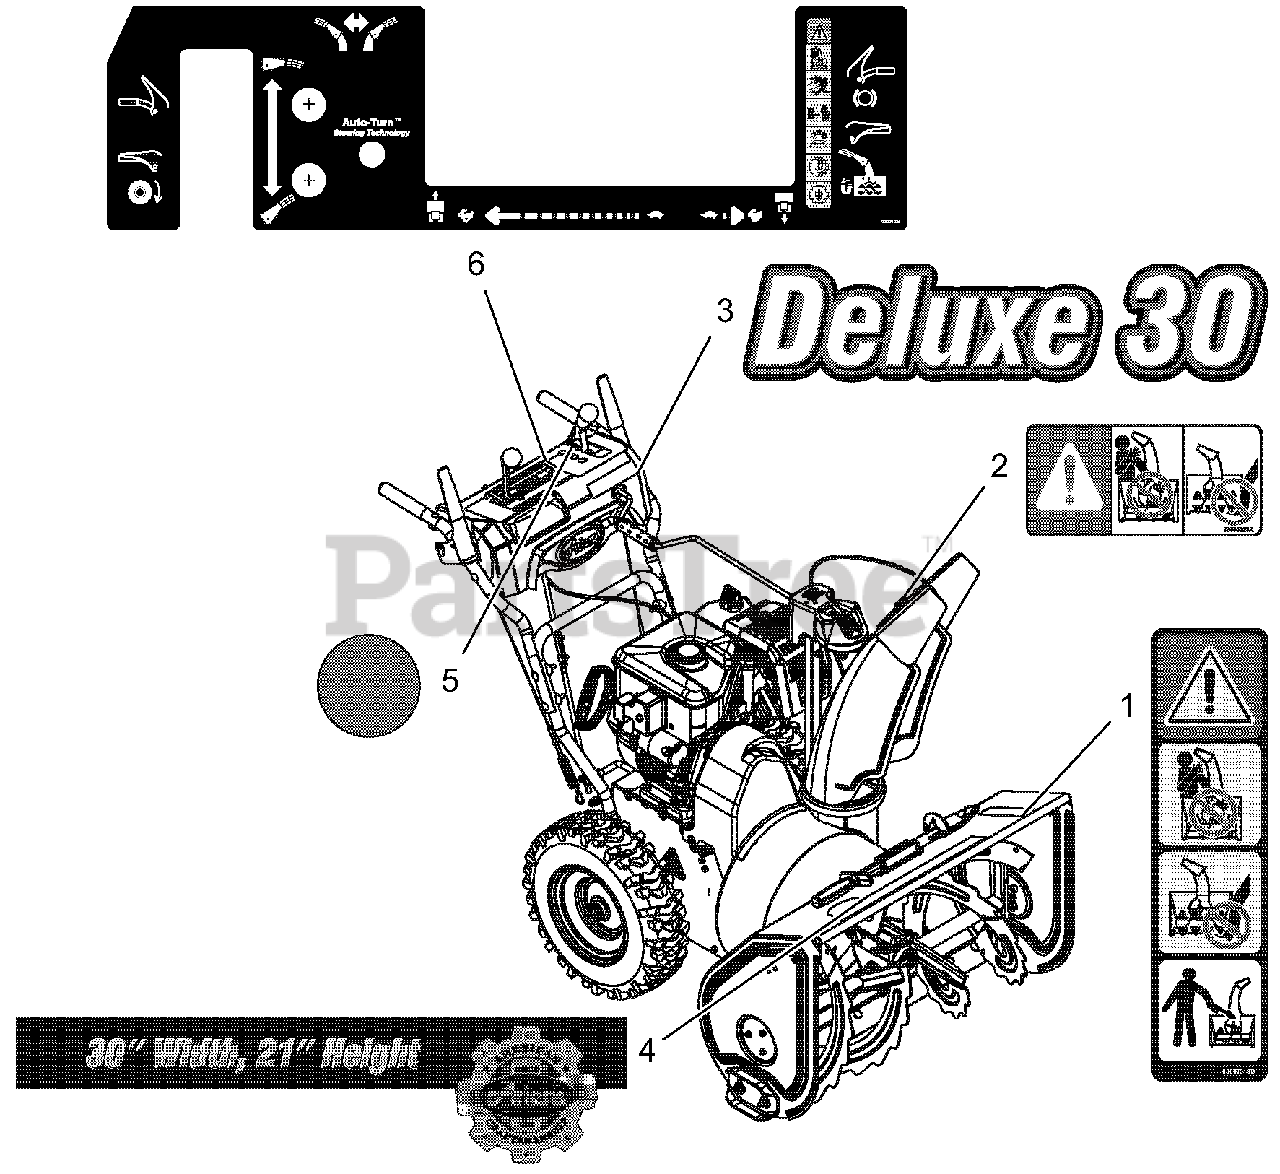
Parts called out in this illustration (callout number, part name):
1	DECAL, DANGER - ROTATING PARTS
2	DECAL, DANGER
3	DECAL, DELUXE 30
5	DECAL,AUTODIFFERENTIAL
6	DECAL,CONTROL-SML,AT,ID
